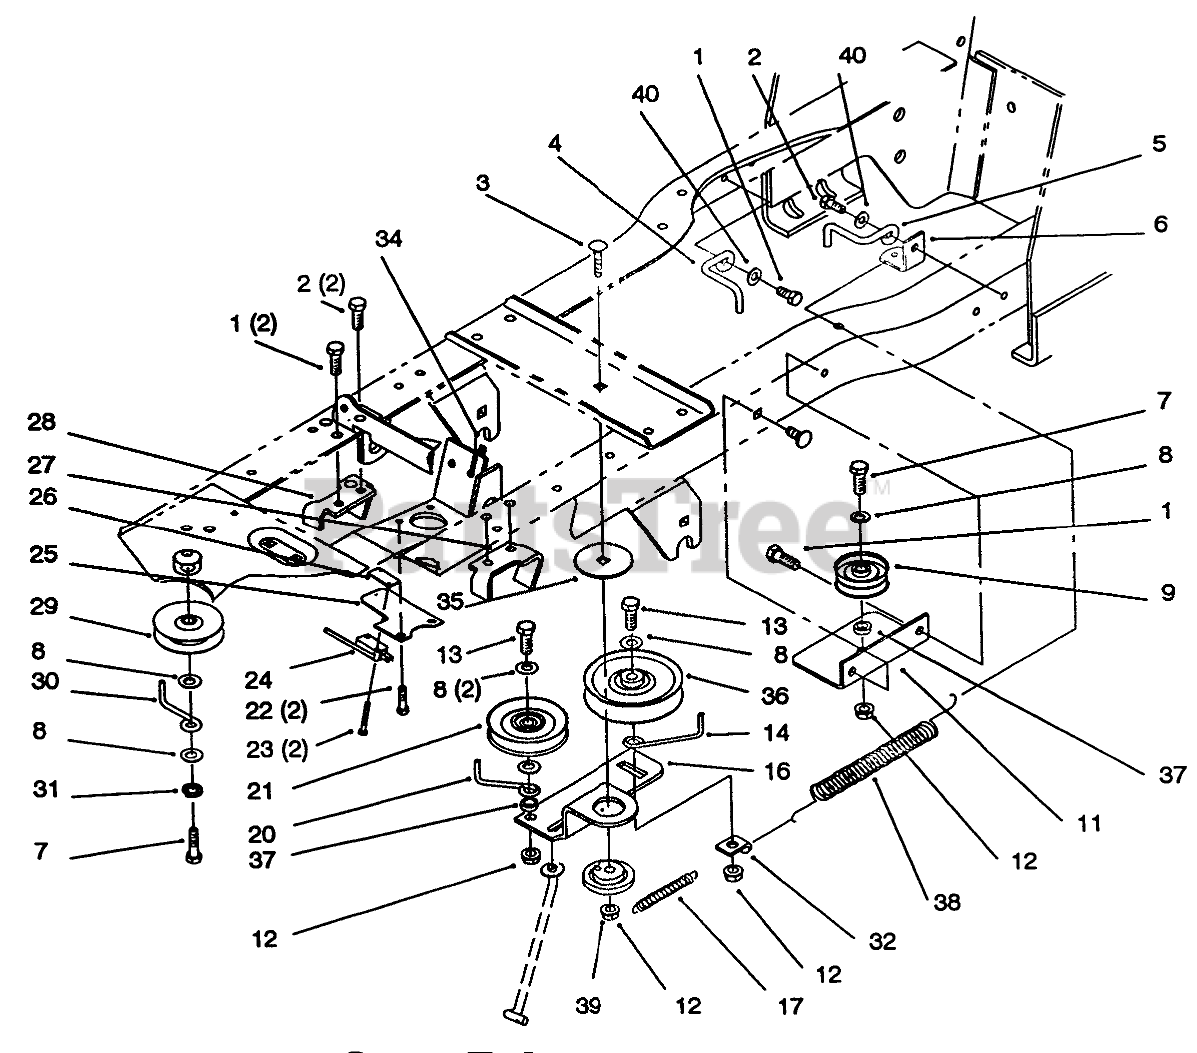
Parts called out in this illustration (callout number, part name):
1	Screw-HH (Only On: 72042, 72062)
2	Screw-TAF (Only On: 72042, 72042, 72062)
3	Screw-CARR (Only On: 72042, ,2062)
4	Guide-Belt RH (Only On: 72042, 72062)
5	Guide-Belt LH (Only On: 72042, 72062)
6	Bracket-Idler Spring (Only On: 72042, 72062)
7	Screw-HH (Only On: 72042, 72062)
8	Washer-Flat (Only On: 72042, 72062)
9	Pulley-Idler (Only On: 72042, 72062)
11	Bracket-Idler Rear (Only On: 72042, 72062)
12	Nut-Hex Loek (Only On: 72042, 72062)
13	Screw (Only On: 72042, 72062)
14	Guide-Belt (Only On: 72042, 72062)
16	Arm-Idler (Only On: 72042, 72062)
17	Spring-Extension (Only On: 72042, 72062)
20	Guide-Belt (Only On: 72042, 72062)
21	Pulley-Idler (Only On: 72042, 72062)
22	Screw-TAP (Only On: 72042, 72062)
23	Screw (Only On: 72042, 72062)
24	Switch-Micro (Only On: 72042, 72062)
25	Bracket-Microswitch (Only On: 72042, 72062)
26	Nut-Speed (Only On: 72042, 72062)
27	Bracket-Clutch (Only On: 72042, 72062)
28	Bracket-Brake (Only On: 72042, 72062)
29	Pulley-Idler (Only On: 72042, 72062)
30	Guide-Belt (Only On: 72042, 72062)
31	Washer-Lock (Only On: 72042, 72062)
32	Clip-Spring (Only On: 72042, 72062)
34	Tie Strap (Only On: 72042, 72062)
35	Washer-Bearing (Only On: 72042, 72062)
36	Pulley-Flat Idler (Only On: 72042, 72062)
37	Spacer (Only On: 72042, 72062)
38	Spring-Extension (Only On: 72042, 72062)
39	Bushing (Only On: 72042, 72062)
40	Washer-Flat (Only On: 72042, 72062)
